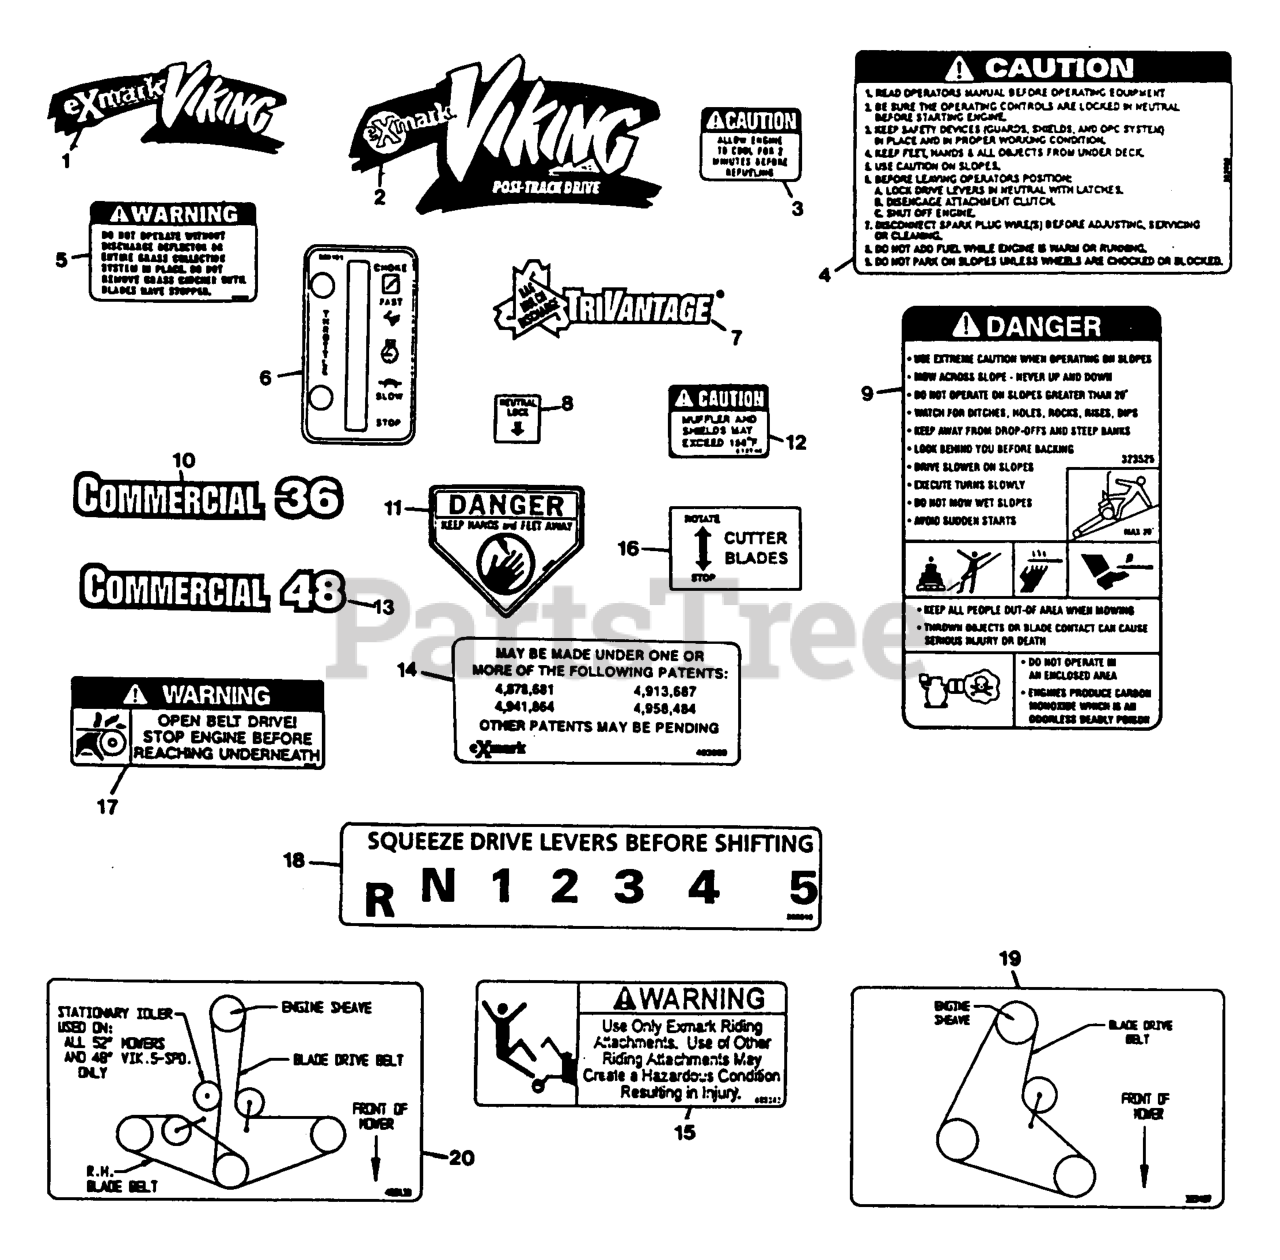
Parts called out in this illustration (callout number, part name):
4	LABEL,INSTRUCTION
5	DECAL-WARNING, DISCHARGE
8	DECAL,NEUTRAL LOCK
10	DECAL,COMMERCIAL 36
11	DECAL-DANGER
13	DECAL,COMMERCIAL 48
15	DECAL,SULKY WARNING
16	DECAL,CUTTER BLADE
17	DECAL,BELT DRIVE
18	DECAL,SHIFTER
19	DECAL,BELT ROUTING 32/36
